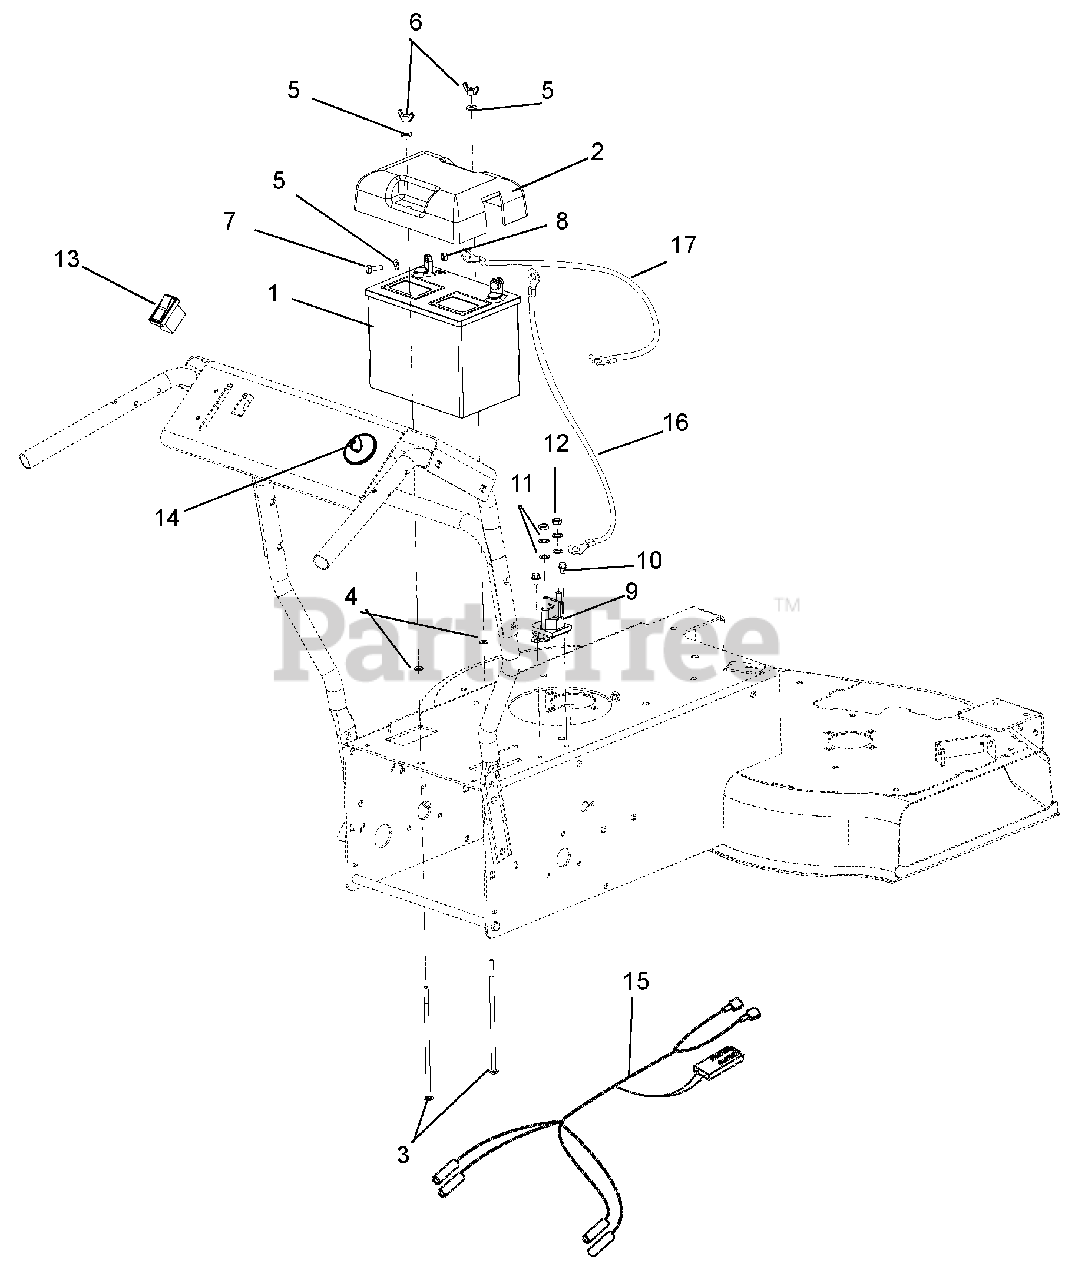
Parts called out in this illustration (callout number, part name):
1	BATTERY-SLI U1B-165
2	COVER, BATTERY
3	@BLT-RDHDSQNK .25-20X7.00 G2YZ
4	NUT-PUSH .25X.50 O.D.
5	@WSHR-FL-STL.281X.62X.065 YWZC
6	NUT-LK WING .250-20 YWZC
7	@BLT-HEX .25-20X.75 GR5 YWZC
8	NUT-KEPS .250-20
9	SOLENOID, HP RTV
10	@SCR-TAP .25-20X.37 HWH YWZ TR
11	WSHR-LOCK INT .31 YWZC
12	NUT-JAM .31-24 YWZC
13	SWITCH-ROCKER, MOMENTARY
14	KEYSWITCH-IGNITION 3 POS
15	HARNESS - WAW WIRING
16	STARTER CABLE 6.75"
17	GROUND CABLE
